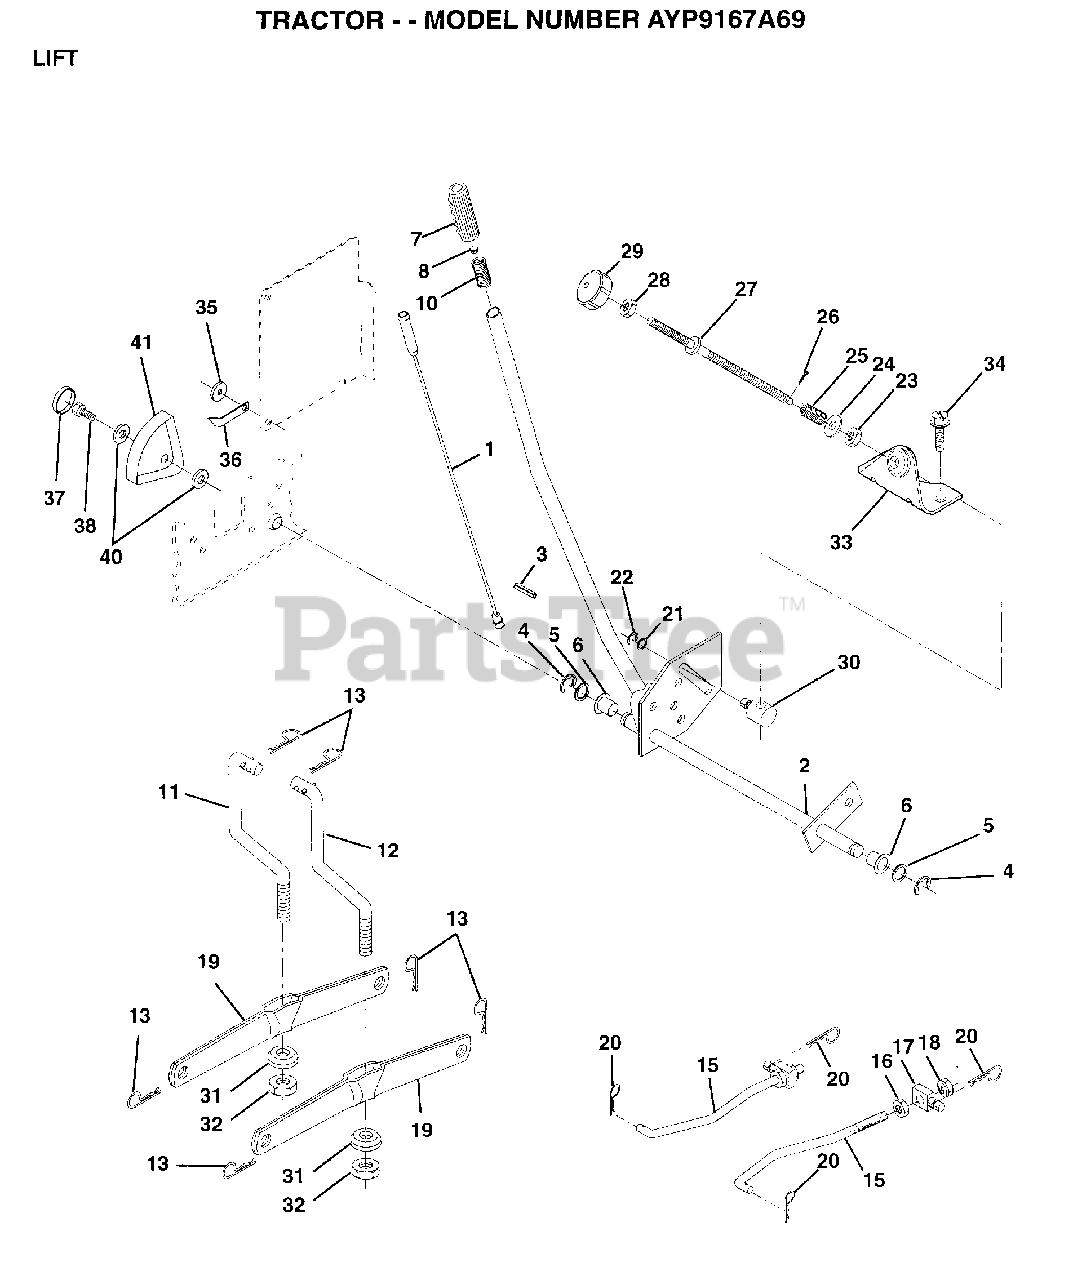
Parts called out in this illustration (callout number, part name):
1	WIRE ASM
2	HANDLE.LIFT.LH.
3	PIN GROOVE
5	WASHER
6	NYLON BEARING
7	GRIP HANDLE
15	LINK.FRONT
16	NUT
17	TRUNION
18	NUT.LK.W/WSH.1/2.
19	ARM SUSP REAR
20	RETAINER.SPRING
21	WASHER
22	KLIP RING
23	NUT T
25	SPRING T
27	WASHER
28	NUT
29	KNOB INF 3/8-16
30	TRUNION LT
31	BEARING PVT LH
32	NUT.CROWNLOCK.3/8
33	BRACKET STOP INF
34	SCREW LT
35	WASHER T
36	POINTER HGT IND
37	"PLUG,HOLE"
38	SCREW
40	WASHER
41	HEIGHT INDICATOR
